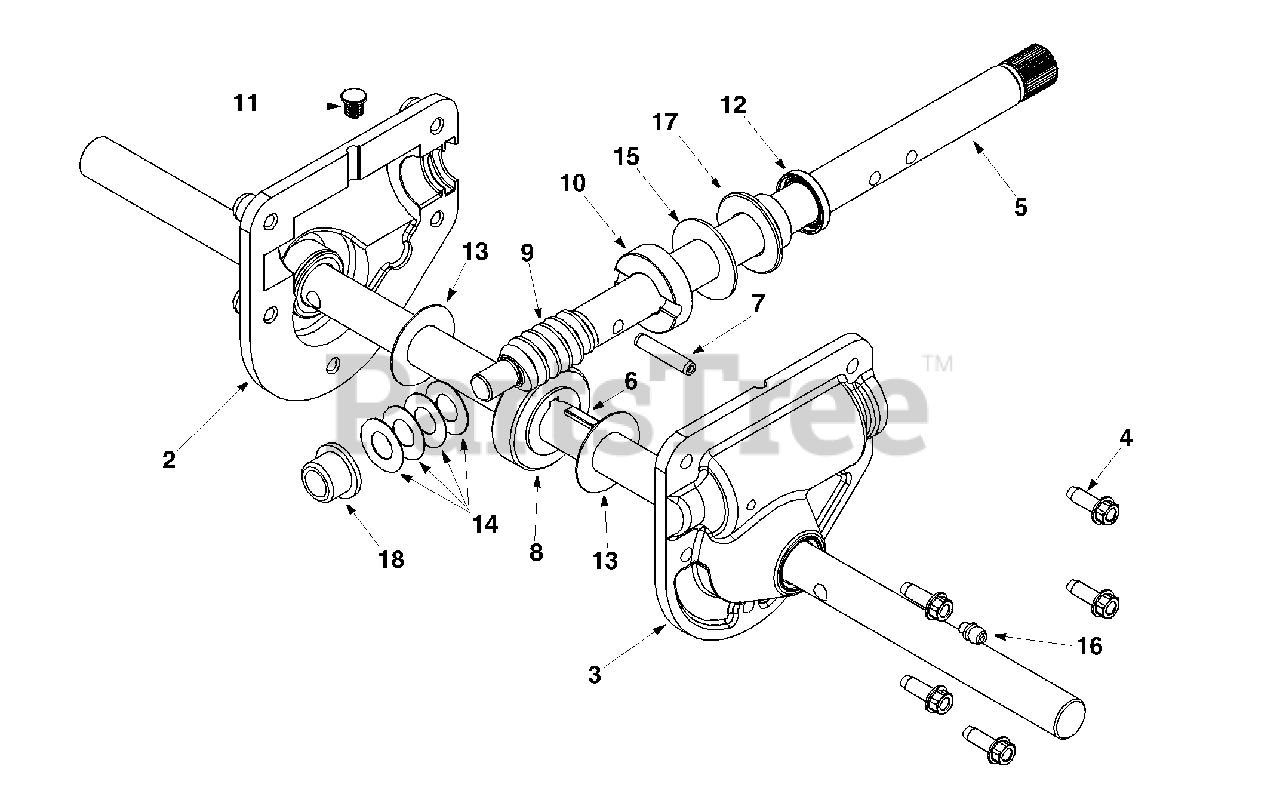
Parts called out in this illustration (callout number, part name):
1	Auger Gearbox Ass'y Comp.
2	Housing Assembly, RH
3	Housing Assembly, LH
4	Screw, 1/4-20 x .75
5	Worm Shaft .75 O.D.
6	Hi-Pro Key
7	Spirol Pin
8	Worm Gear 20T
10	Thrust .75 I.D. x .415 O.D.
11	Plug 1/4 x .437
12	Oil Seal .75 I.D. x 1.73 O.D.
13	Fl-Wash. .760 I.D. x 1.5 O.D.
14	Fl-Wash. .508 I.D. x 1.0 O.D.
15	Fl-Wash. .76 I.D. x 1.50 O.D.
16	Lube Fitting 3/16 Drive
17	Flange Bearing
18	Flange Bearing
